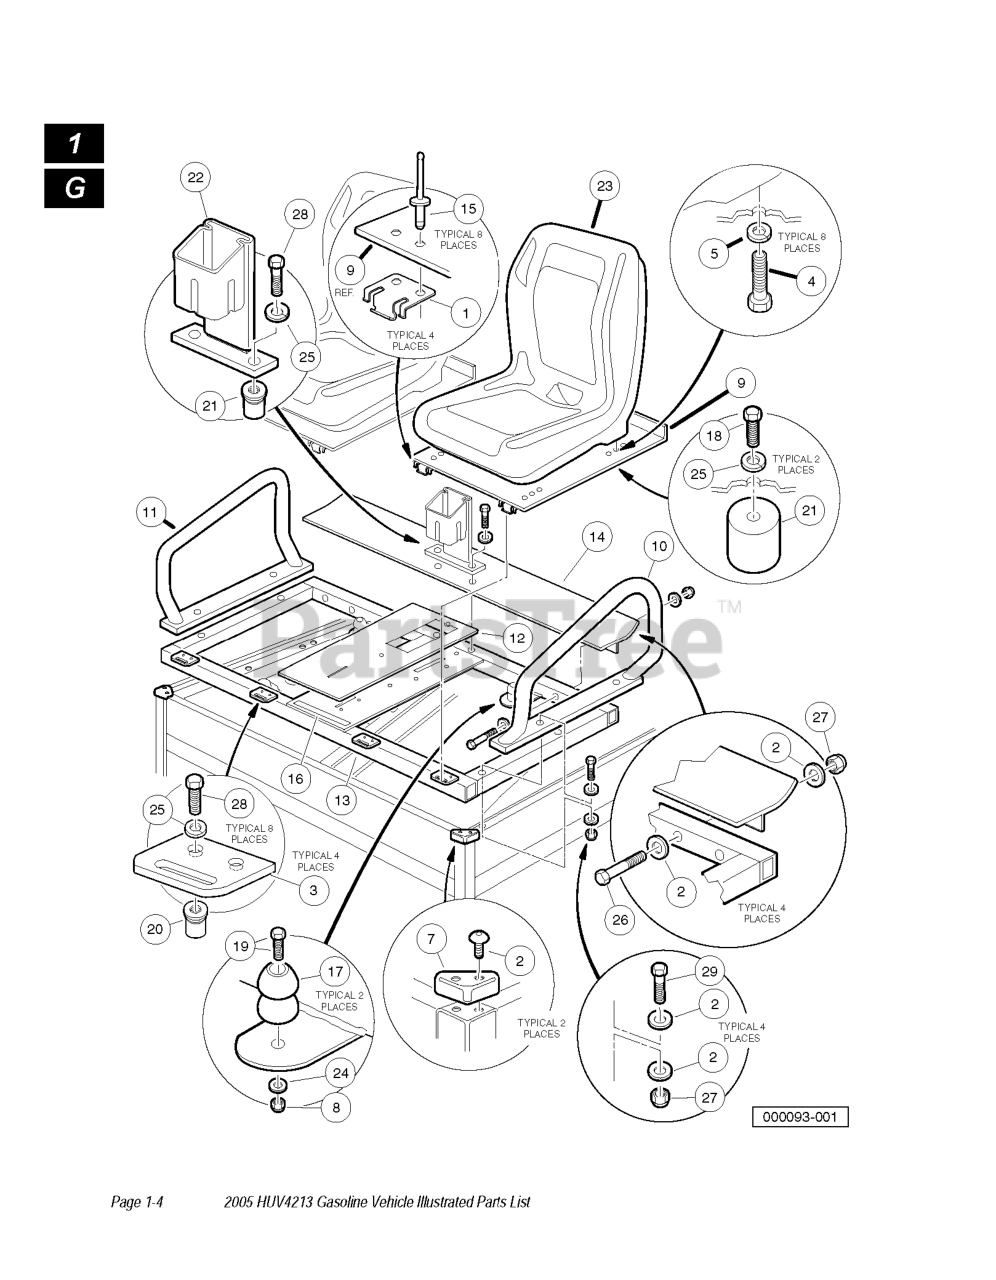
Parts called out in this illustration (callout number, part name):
1	HINGE PLATE
2	WASHER, 5/16 FLAT
3	BODY, HINGE PLATE
4	SCREW, M8-125 X 22 HEX GR.8.8
7	CORNER CAP CAI
8	LOCKNUT, M6-1.00 NYLON INSERT
10	ARMREST DRIVER
11	ARMREST PASSENGER
12	CONSOLE COVER
13	ASM, SEAT SUPPORT - COYOTE STR
15	RIVET, 1/4 X .438 BLIND
17	SEAT HOLDER BASE
18	SCREW, 6M-1.00 X 10MM HEX HEAD
19	SCREW, 6M-1.00 X 35MM HEX HEAD
20	THREADED INSERT
21	SEAT HOLDER CUP
22	RADIO/BEVERAGE HOLDER ASM
23	SEAT, BUCKET, GRAY
24	WASHER 1/4 FLAT
25	LOCKWASHER, 1/4 HELICAL SPLIT
26	SCREW, 1/4-20 X 2.00 HX HD CAP
27	LOCKNUT, 5/16-18 NYLON INSERT
28	SCREW, 1/4-20 X .75 HEX
29	SCREW, 5/16-18 X 2.25
